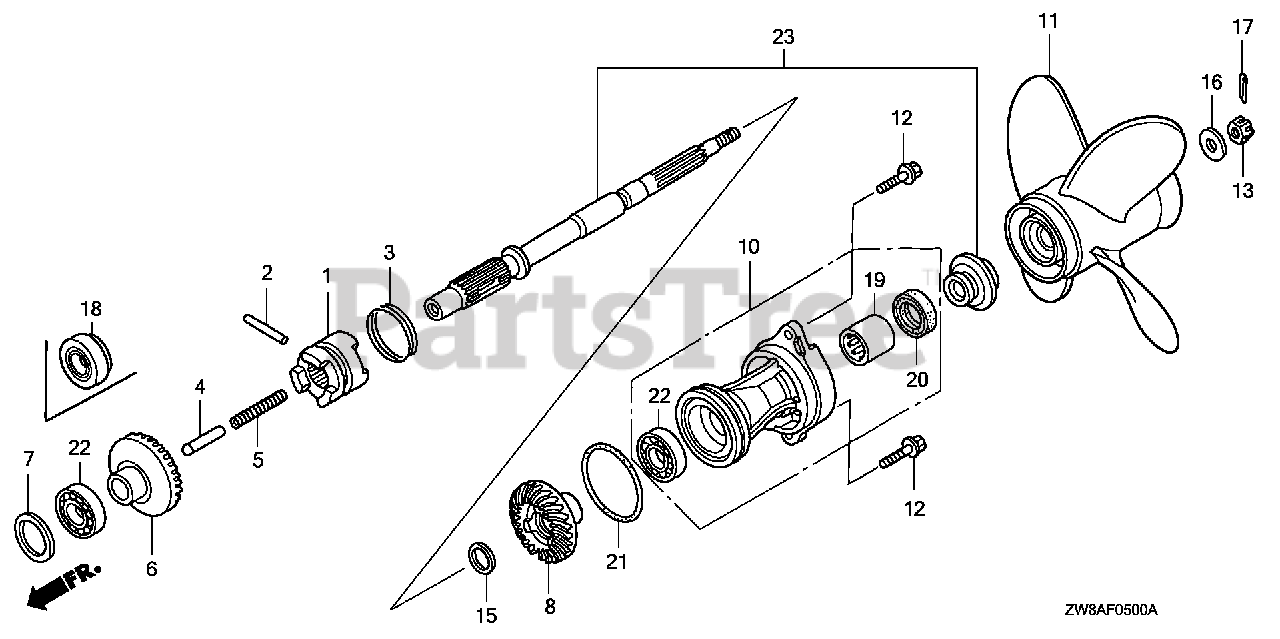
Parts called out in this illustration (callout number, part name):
1	SHIFTER, CLUTCH
2	PIN, SHIFTER (4X30)
3	RING, CROSS PIN
4	SLIDER, SHIFT
5	SPRING, SHIFT
6	GEAR, FR. BEVEL
7	SHIM A (40MM)
7	SHIM B (40MM)
7	SHIM C (40MM)
7	SHIM D (40MM)
8	GEAR, RR. BEVEL
9	SHAFT KIT, PROPELLER
10	HOLDER ASSY., PROPELLER SHAFT *NH282MU* (OYSTER SILVER METALLIC-U)
11	PROPELLER, FOUR BLADES (10X6-1/2 HT) *NH283* (STIN GRAY)
11	PROPELLER, FOUR BLADES (9-1/4X7) *NH283* (STIN GRAY)
11	PROPELLER, FOUR BLADES (9-1/4X10) *NH283* (STIN GRAY)
11	PROPELLER, FOUR BLADES (9-1/4X8) *NH283* (STIN GRAY)
11	PROPELLER, FOUR BLADES (9-1/4X9) *NH283* (STIN GRAY)
11	PROPELLER, FOUR BLADES (9-1/4X11) *NH283* (STIN GRAY)
12	BOLT, FLANGE (6X20)
13	NUT, CASTLE (10MM)
14	WASHER, PROPELLER THRUST
15	WASHER (18MM)
16	WASHER (10MM)
17	PIN, SPLIT (3MM)
18	BEARING (25X47X15)
19	BEARING, NEEDLE (17X24X20) (NTN)
20	SEAL, WATER (17MM) (NOK)
20	SEAL, WATER (17MM)
21	O-RING (59.4X3.1)
22	BEARING, RADIAL BALL (6005)
23	SHAFT KIT, PROPELLER
